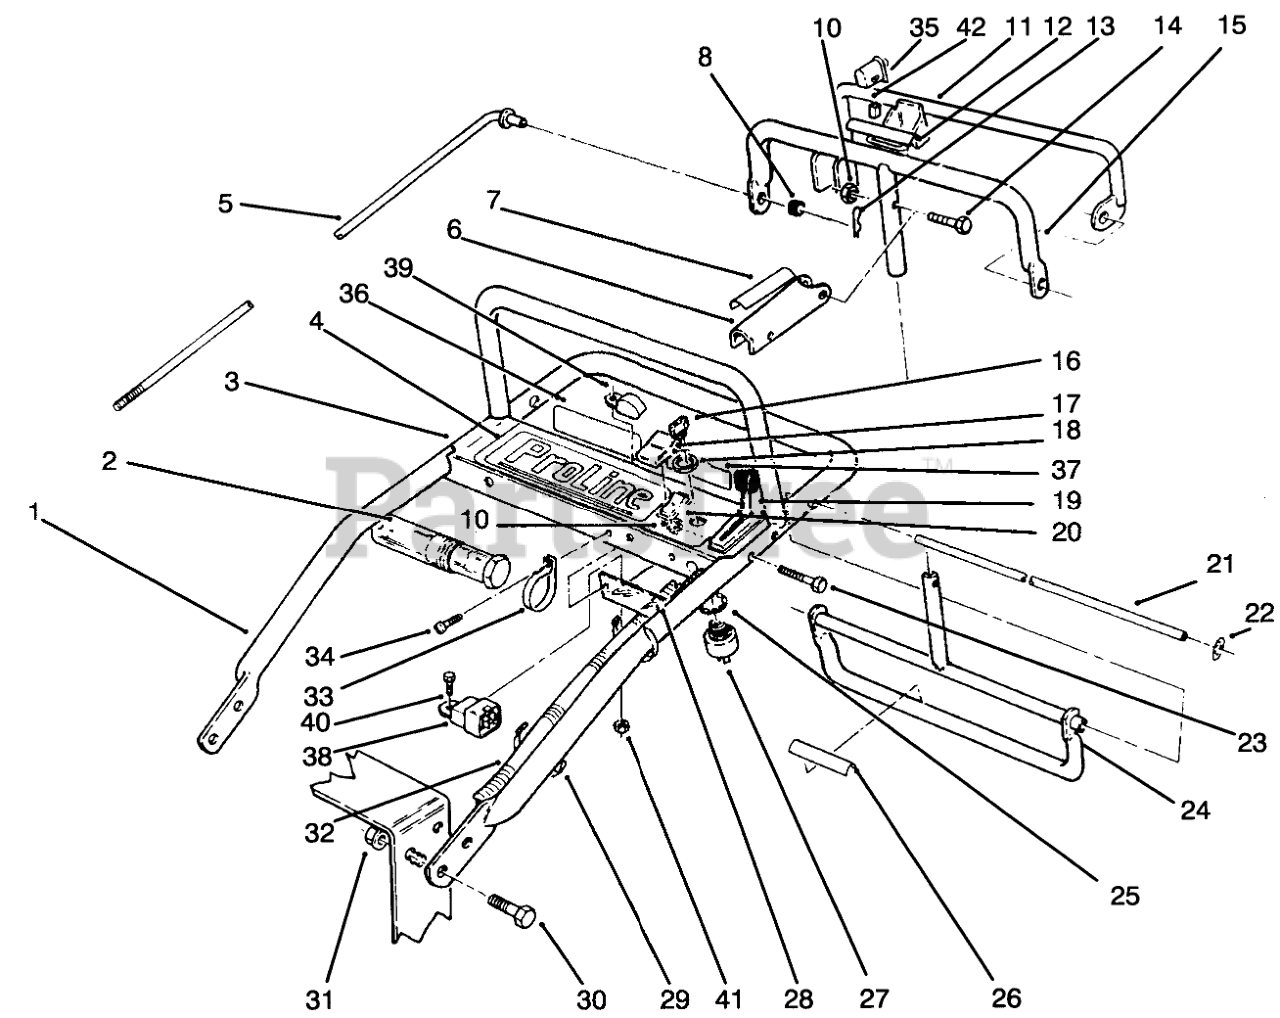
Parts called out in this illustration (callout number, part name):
1	Handle-Upper
2	TUBE-MANUAL
3	Panel-Control
4	DECAL-CONTROL PANEL
5	ROD-CONTROL
6	Lever-Parking Brake
7	DECAL-LEVER, PARKING
8	GROMMET-RUBBER
10	NUT-LOCK, NI
11	Bail
12	DECAL
13	PIN-COTTER
14	SCREW-SHH
15	Bar
16	KEY-IGNITION
17	BOOT-SWITCH
18	NUT-HH
19	CONTROL-THROTTLE
20	SWITCH
21	PIVOT ROD
22	Ring-Push On
23	SCREW-SHH
24	Control Pivot
25	WASHER-TOOTH, INTERNAL
26	DECAL
27	Switch-Off/On (Incl. Ref. #16, 18, & 25)
28	Panel-Bottom
29	TIE-CABLE
30	SCREW-HHF
31	NUT-HF
32	Wire Harness
33	CLAMP-R
34	SCREW-SHWH
35	SWITCH-BAIL
36	DECAL-INSTRUCTION, SAFETY
37	DECAL-INSTRUCTION
38	RELAY
39	Module
40	SCREW-HH
41	NUT-LOCK, NI
42	CONNECTOR-BODY
